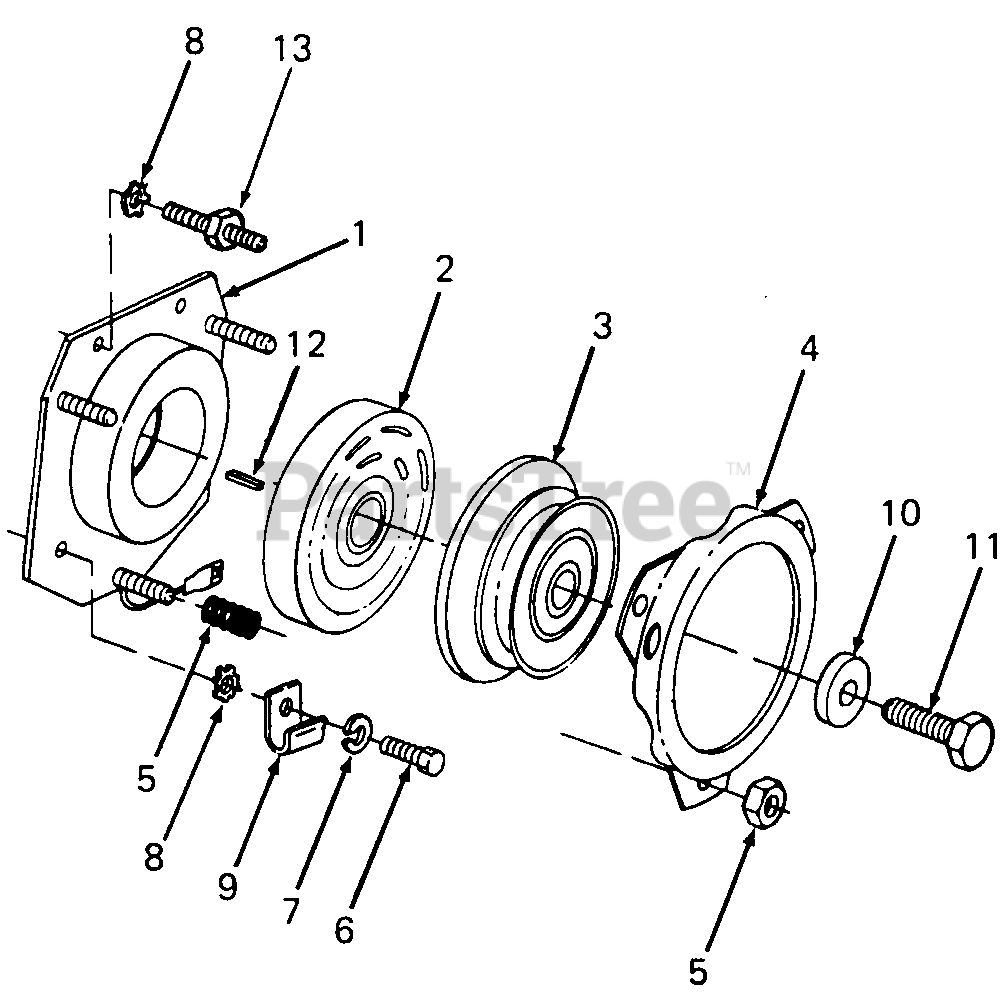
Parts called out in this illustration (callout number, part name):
4	Drum, Brake
5	Spring & Nut Kit
6	Screw, Hex Cap, 7/16-14 X .75 Lg GR5
7	Washer, Lock, 7/16
8	Washer, Ext. Lock, .45 X .75 X .035 Thk
9	Clamp, Cable
10	Washer, Flat, .47 X 1.5 X .225 Thk
11	Screw, Hex Cap, 7/16-20 X 1.25 Lg GR5
12	Key, Square, 1/4 X .75 Lg
13	Stud, 7/16-14 Trd
